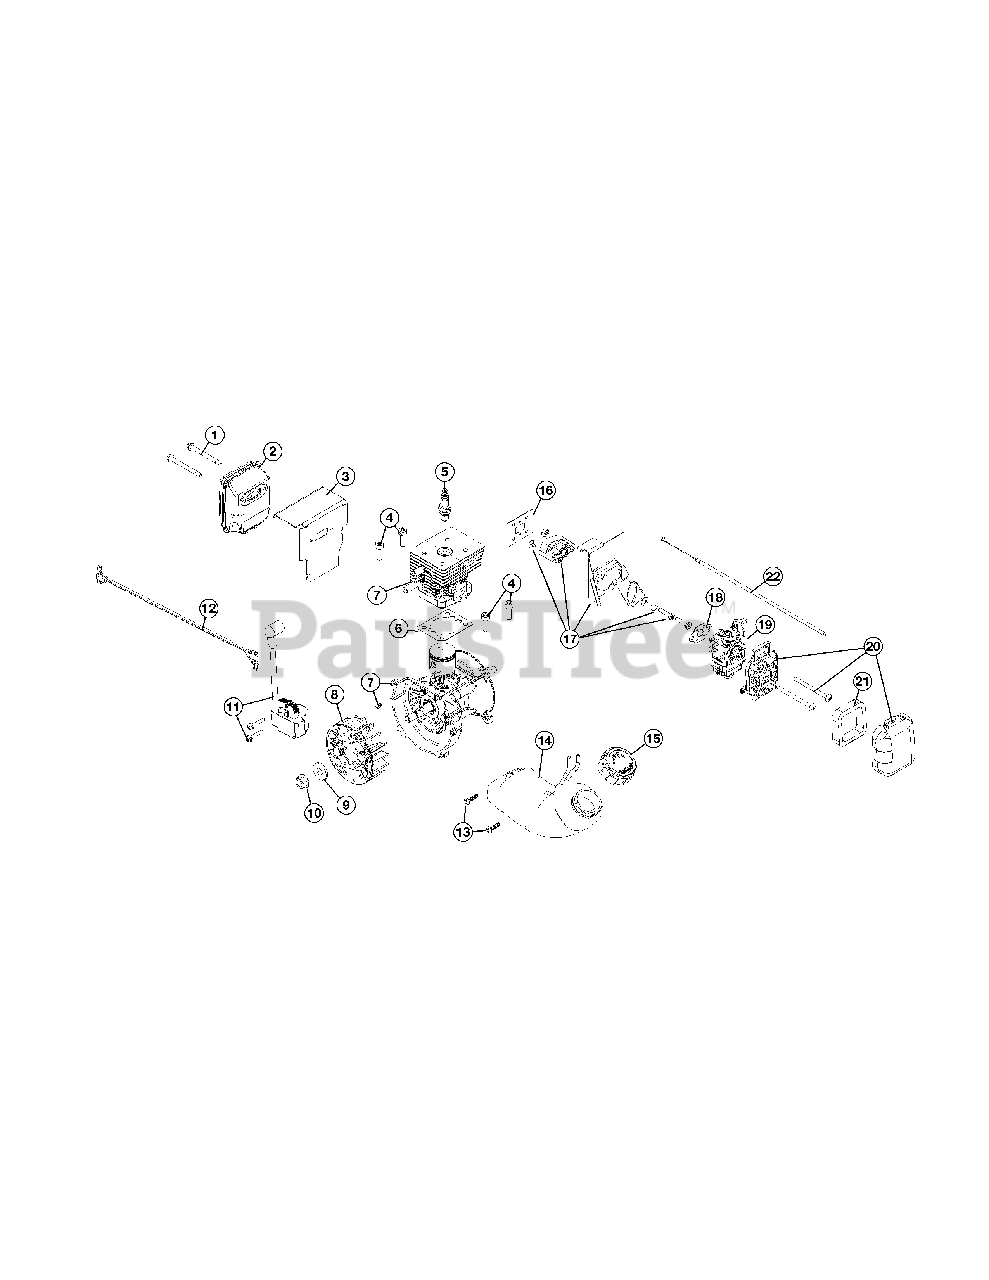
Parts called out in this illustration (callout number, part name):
1	Muffler Screws
2	Muffler Assembly (Incl. 1 & 3)
3	Muffler Gasket
5	Spark Plug
6	Cylinder Gasket
7	Shortblock Assembly (Incl. 4-6 & 8-11)
8	Flywheel Assembly
9	Washer
11	Module Assembly
12	Lead Wire
14	Fuel Tank Assembly (Incl. 13 & 15)
15	Fuel Cap
16	Insulator Gasket
17	Insulator Assembly (Incl. 16)
18	Carburetor Gasket
19	Carburetor Assembly (Incl. 18)
20	Aircleaner Assembly (Incl. 21)
21	Air Filter
22	Throttle Cable
